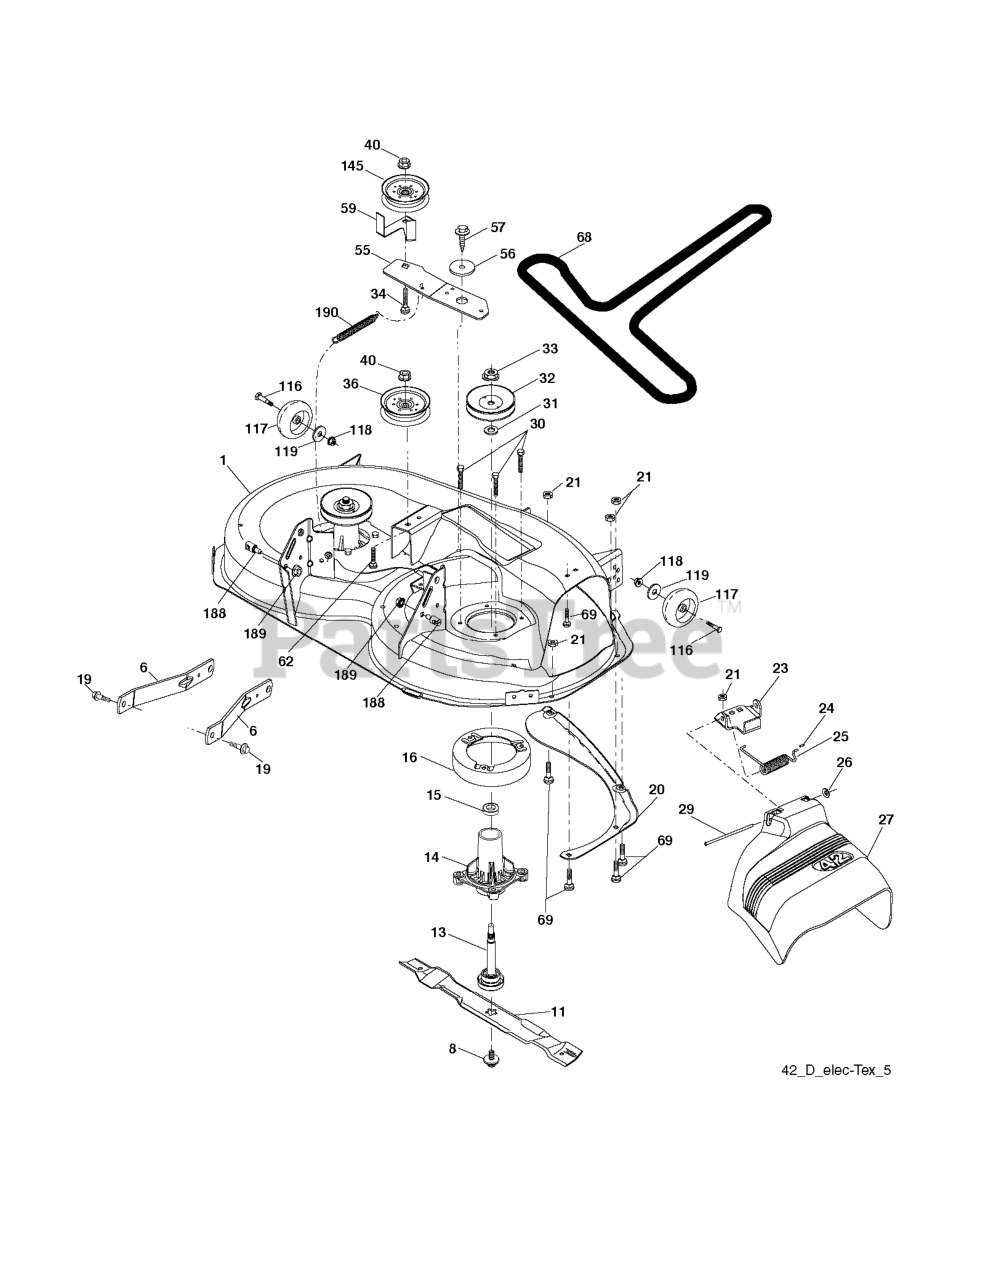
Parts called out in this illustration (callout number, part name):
1	DECK.WELDMENT.42"
6	ARM.SUSPENSION.MOWER.R
8	BOLT.WASHER.ASM.7/16-2
11	42" HI-LIFT BLADE
13	SHAFT.ASM.MDRL.N/GREASE.38
14	RP.HOUSING.MANDREL.4PT.
16	STRIPPER.MANDREL.ROUND.BLACK
19	BOLT.SHOULDER
20	BAFFLE.VORTEX
21	LOCKNUT
23	BRKT.DEFLECTOR.38"2005+
24	CAP-SLEEVE LT
25	SPRING.TORSION.DEFLECT
26	NUT PUSH M
27	SHIELD.DEFLECTOR.MOWER.42"BLAC
29	ROD.HINGE
30	SCREW, WASHER HEAD
31	WASHER.SPACER.MANDREL
32	PULLEY/MANDREL
33	NUT.FLANGE.LOCK.TOP
34	BOLT.3/8-16X1.50
36	PULLEY.IDLER.2006
40	NUT LOCK FLG 3/8-16 UNC
56	SPACER.RETAINER
57	SCREW 3/8-16X1
59	GUARD, BELT
68	BELT V SECONDARY
69	BOLT
116	BOLT.SHLD."A"2.41."B"1.66
117	WHEEL.GAGE.HALF.SPOKED
118	NUT LOCK FLG 3/8-16 UNC
119	WASHER.5/16.FLAT.STE.STD.
145	PULLEY.IDLER.48"PRIMARY
188	STUD.FASTNER.W/ANTI-ROTATE
189	NUT LOCK HEX FLANGE 5/16-18
190	SPRING.MOWER.DRIVE.ELECTRIC
